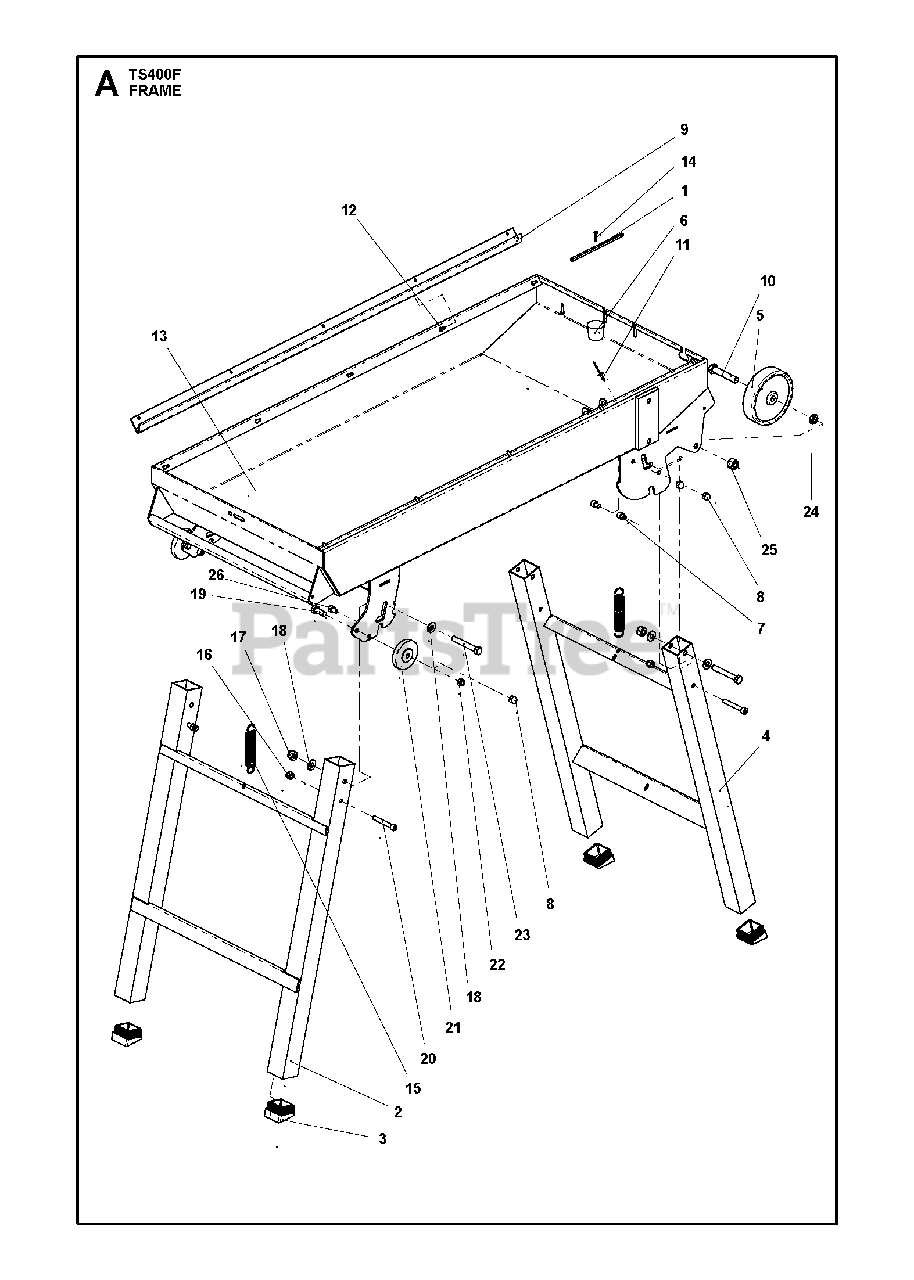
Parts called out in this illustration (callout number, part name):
1	CHAINE BT1 D/1.4(0.15 mm)
3	FEET PAD ON TS350E/TS400***543
16	HEXAGON LOCKING NUT
17	HEXAGON LOCKING NUT
18	WASHER
21	GALET LISSE 65/10/24.8/
